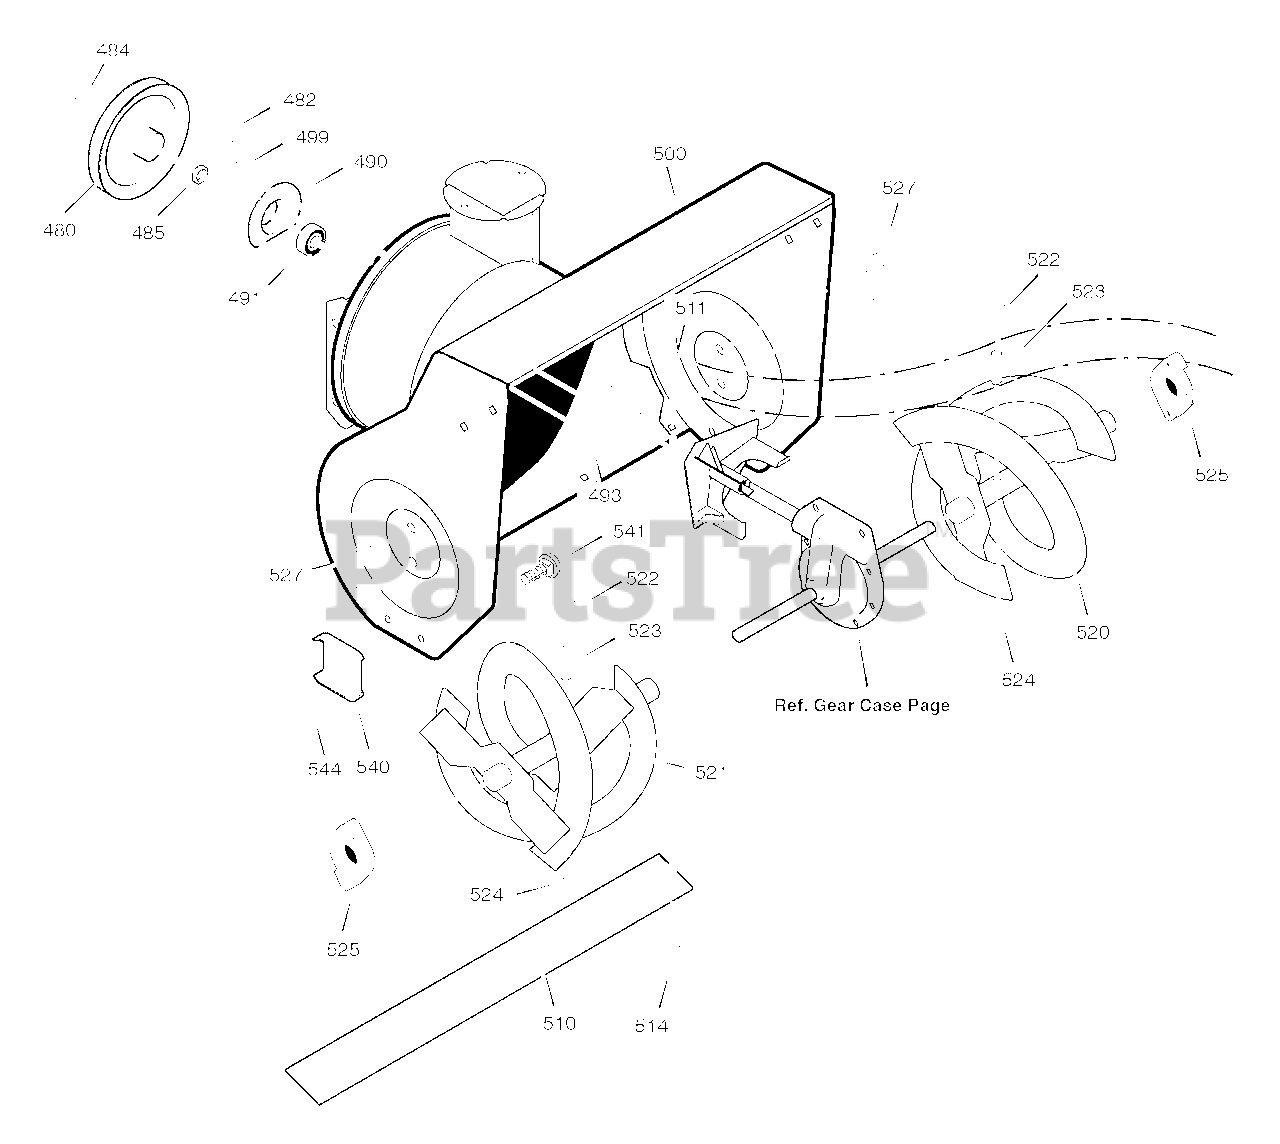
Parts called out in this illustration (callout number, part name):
480	PULLEY, 4L 8.40 OD
482	KEY, SQUARE 3/16 X 3/4
484	NUT, 1/2-20
485	SPACER, FRICTION PULLEY
490	RETAINER, BALL BRNG
491	BEARING, BALL
493	BOLT, HEX 5/16-18X .50
499	NUT, 5/16-18 HEXWDFLLK
500	HOUSING, ASSY
510	BLADE, SCRAPER
511	BOLT, 5/16-18X.75
514	NUT, 5/16-18
520	AUGER, ASSY, LH
521	AUGER, ASSY, RH
522	SCREW, 1/4-20 X 1.75
523	SPACER, SLEEVE
524	NUT, 1/4-20
525	BEARING, FLANGE
527	SCREW, 5/16-18 x 0.75
540	SKID, HEIGHT ADJUST
541	BOLT, 5/16-18 X .75
544	NUT, 5/16-18
